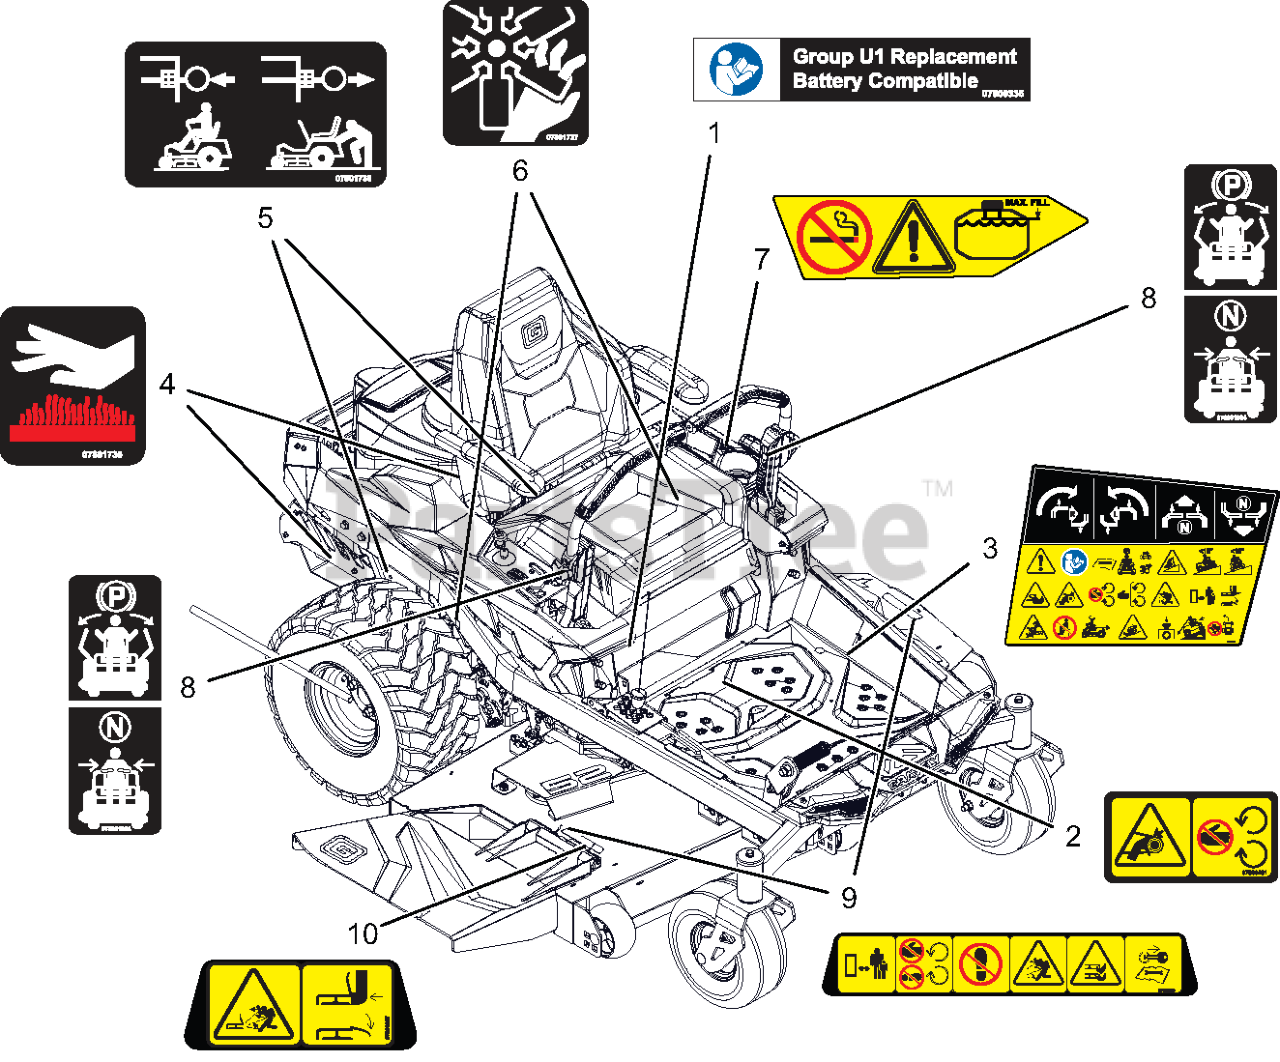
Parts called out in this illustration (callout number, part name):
1	DECAL, U1 BATTERY REPLACEMENT
2	DECAL, SAFETY - GUARDING
3	DECAL- MAIN SAFETY-INSTRUCTION
4	DECAL,SAFETY HOT SURFACE
5	DECAL,TRANSAXLE DISCONNECT
6	DECAL, DANGER FAN
7	DECAL, FUEL WARNING
8	DECAL- STEERING-BRAKE
9	DECAL- SAFETY - MOWER DECK
10	DECAL- SAFETY - DECK GUARDING
